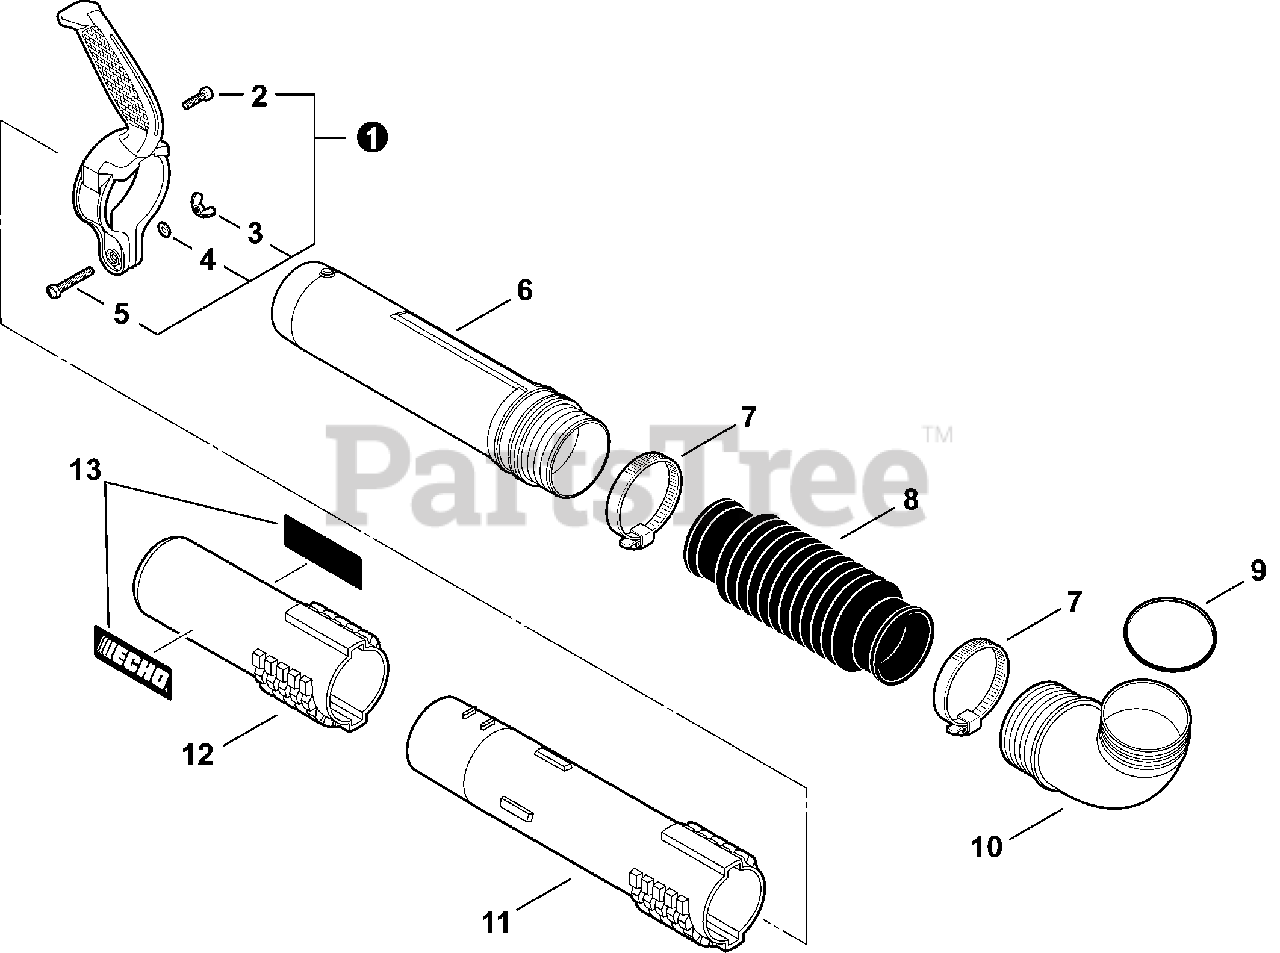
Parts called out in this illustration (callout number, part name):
1	BLOWER TUBE HELPER HANDLE ASSY
2	SCREW - 4X16 -- TAPPING
3	WINGNUT - 6
4	WASHER - 6
5	BOLT - 6X25
6	TUBE, BLOWER - SWIVEL
7	CLAMP, HOSE
8	TUBE - FLEXIBLE
10	TUBE, BLOWER - ELBOW
11	TUBE, BLOWER - STRAIGHT
12	TUBE, BLOWER - NOZZLE
13	LABEL - ECHO
